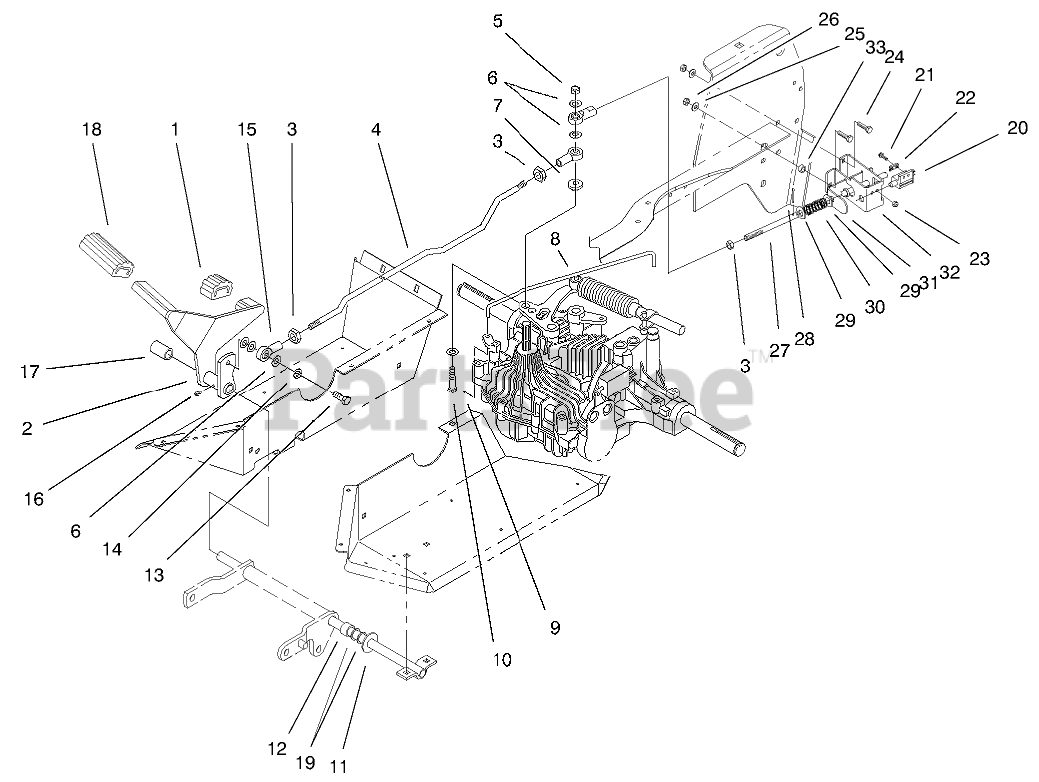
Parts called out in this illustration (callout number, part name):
1	PAD-PEDAL
2	PEDAL-HYDRO WA
3	NUT-HJ
4	ROD - HYDRO
5	NUT-LOCK, NI
6	WASHER-FLAT
7	BUSHING
8	ROD - BYPASS
9	PIN-COTTER
10	SCREW-HH
11	WASHER
12	SPACER
13	SCREW-HH
14	WASHER-LOCK
15	END-ROD, FEMALE
16	FITTING-GREASE
17	SPACER
18	PAD-PEDAL
19	WASHER-FLAT
20	SWITCH-POLE, SINGLE
21	SCREW-SHH
22	RETAINER-SCREW
23	NUT-LOCK
24	SCREW-HH
25	WASHER-FLAT
26	NUT-LOCK, NI
27	ROD-NMIR
28	PIN-COTTER
29	WASHER-FLAT
30	SPRING-COMPRESSION
31	Arm-Push
32	BRACKET, NMIR
33	SPACER-YOKE, RIGHT
